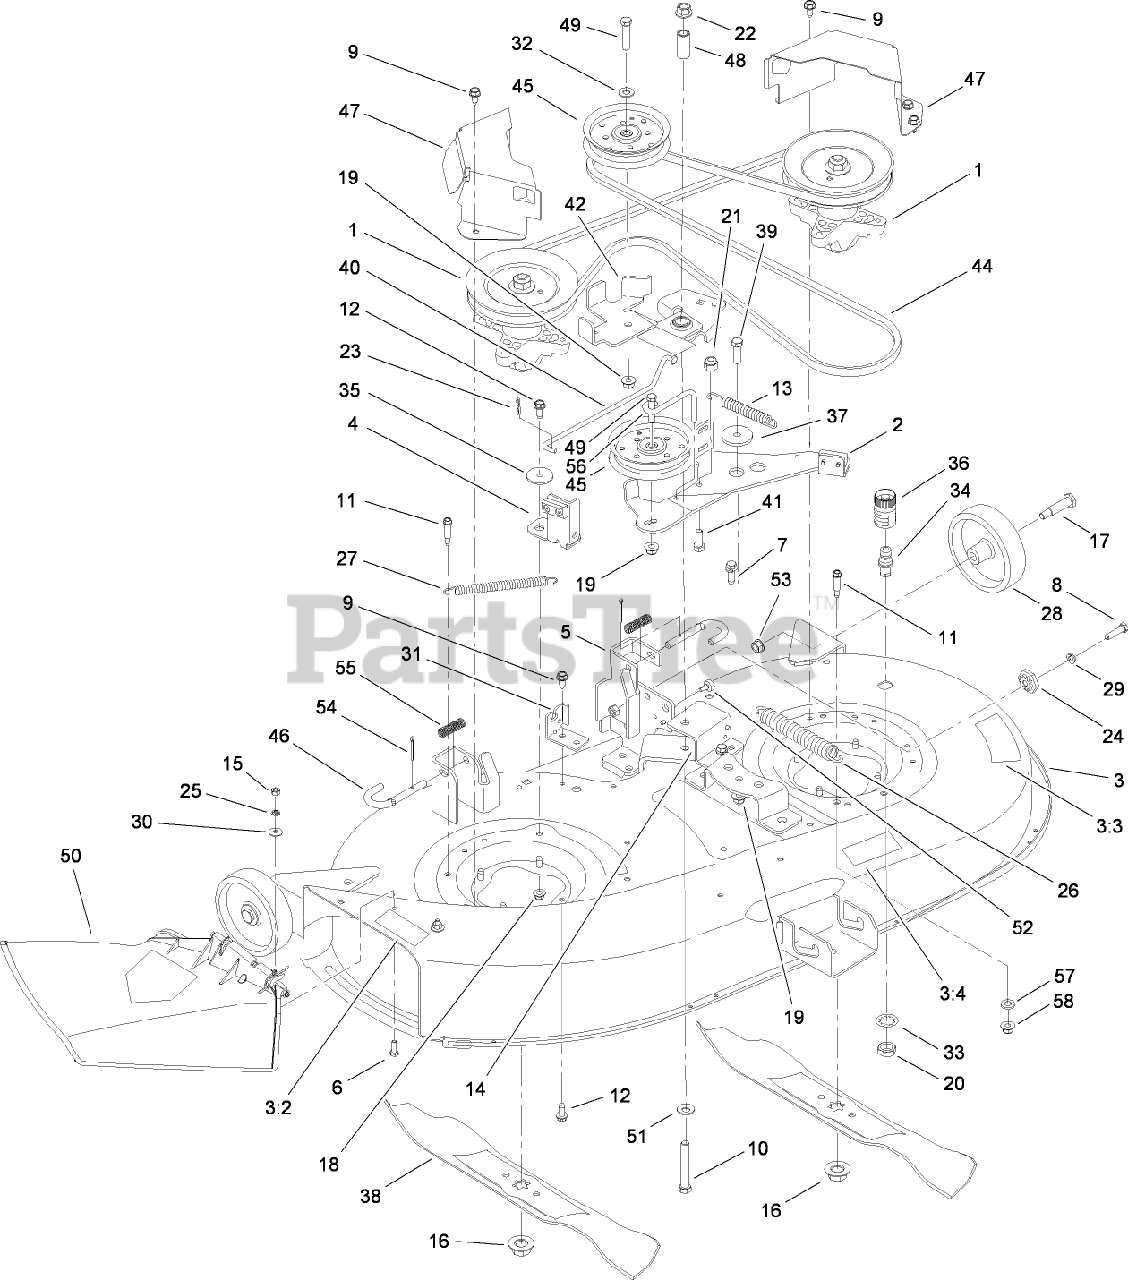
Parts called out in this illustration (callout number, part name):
1	SPINDLE ASM
2	DECK BRAKE ASM
3	DECK AND DECAL ASM
3:2	DECAL-DANGER
3:3	DECAL-DANGER
3:4	DECAL-ROUTING, BELT
4	BRAKE ASM
5	LH HANGER BRACKET ASM
6	SCREW-HH
7	SCREW-TAP
8	SCREW-HH
9	SCREW-HH, TAP
10	SCREW-HH
11	BOLT-SHOULDER
12	SCREW-HWH
13	SPRING-EXTENSION
14	BRACKET-SUPPORT, PIVOT
15	NUT-HEX
16	NUT-LOCK, FLANGE
17	BOLT-SHOULDER
18	NUT-LOCK, FLANGE
19	NUT-LOCK, FLANGE
20	NUT-HEX
21	NUT-LOCK, HEX
22	NUT-LOCK, FLANGE
23	PIN-COTTER
24	GEAR-ADJUSTMENT, DECK
25	RETAINER-BOLT
26	SPRING
27	SPRING-EXTENSION
28	WHEEL-DECK, REAR
29	WASHER-LOCK
30	WASHER-SPRING
32	WASHER-FLAT
33	WASHER-LOCK
34	NOZZLE-WATER, DECK
35	SPACER-SHOULDER
36	ADAPTER-NOZZLE, WATER
37	SPACER-SHOULDER
39	SCREW-HH
40	ROD-BRAKE
41	SCREW-HH
44	BELT-V TYPE
45	PULLEY-IDLER
46	PIN-HANDLE, DECK RELEASE
47	COVER-BELT
48	SPACER
49	SCREW-HH
50	DISCHARGE CHUTE ASM
51	WASHER-BELL
52	BUMPER
53	NUT-LOCK, FLANGE
54	PIN-COTTER
55	SPRING-COMPRESSION
56	ROD-KEEPER, BELT
57	WASHER-FLAT
58	NUT-LOCK, FLANGE
